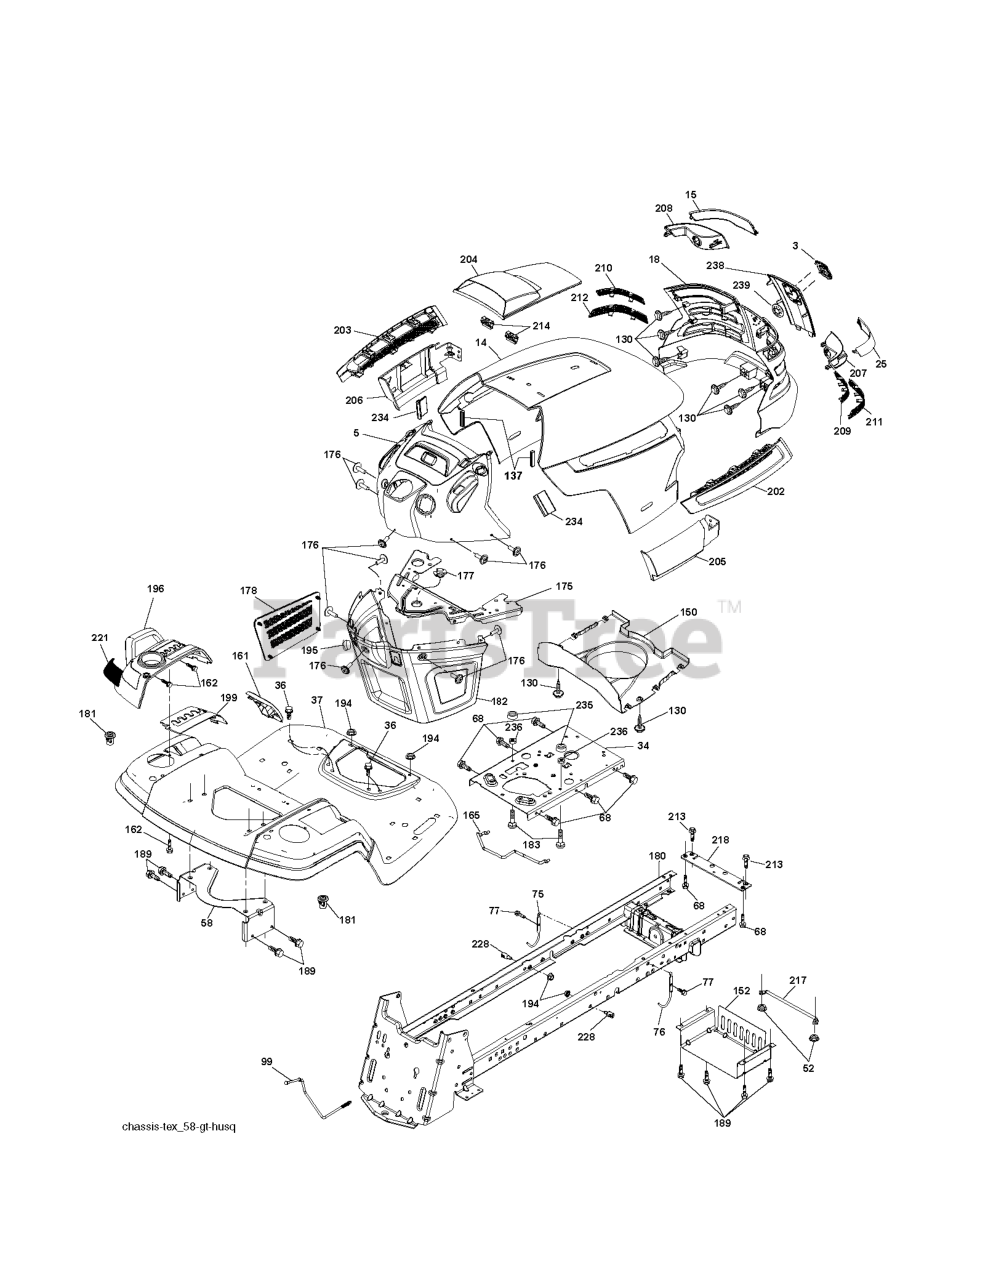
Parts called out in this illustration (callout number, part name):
3	RP LOGO
5	DASH.ASM.HUSQ.GT.E.RECT.W/CK
14	HOOD
15	LENS.LH.TEX.GT.HUSQ.CL
18	GRILL.ASM.HUSQ.TG/CRD.W/TRIM
25	LENS.RH.TEX.GT.HUSQ.CL
34	PLATE.ENGINE.WELDED.CHASSIS
36	SCREW 5/16"
37	FENDER.PNT.TX.GT.CH/FW.ORANGE
52	LOCKNUT
58	BRKT.SUPPORT.FNDR/TANK
68	Screw 5/16-18 x 1/2 Hex, Self Tapping 5/16-18 x 1/2
75	ROD UPSTOP
76	ROD UPSTOP
77	SCREW 3/8-16X1
99	ROD.BYPASS.HYDRO.0510/0610.GT
130	SCREW
137	BUMPER DASH
150	AIR.DUCT.HOOD.TEX.GT.HUSQ
152	SHIELD.BROWNING.W/TEX
161	CONSOLE.FUEL.WINDOW.HU
162	SCREW.HI-LO.CONSOLE
165	SUPPORT.TANK.REAR.W/TEX
175	PLATE.CROSSMEMBER.HUSQ
176	SCREW.#10-24X5/8.RN.QU
177	BUSHING, STEERING
178	CARGO.ASM.NET.TXGT.W/C
180	CHASSIS.GT.SLOPED.DRAWBAR.
181	BUSHING.MNT.FEND.CRGO.
182	DASH.LOWER.COMMON.12V.
183	BOLT.5/16-18X1-1/4 FULL.THREAD
189	SCREW
194	NUT LOCK HEX FLANGE 5/16-18
195	PLUG.HOLE.DASH.LOWER.12V.BLK
196	RP CONSOLE.ASM.DECKLFT.W/
199	PLATE.DECK.LIFT.HUSQVARNA.GT
202	VENT.SIDE.HOOD.HUSQ.RH.GREY
203	VENT.SIDE.HOOD.HUSQ.LH.GRAY
204	VENT.TOP.HOOD.HUSQVARN
205	SKIRT.HOOD.SIDE.HUSQ.RH.GREY
206	SKIRT.HOOD.SIDE.HUSQ.LH.GREY
207	BEZEL.RH.TEX.GT.HUSQ
208	BEZEL.LH.TEX.GT.HUSQ
209	INSERT.HEX.GRILL.HUSQ.GREY
210	INSERT.HEX.GRILL.HUSQ.
211	INSERT.HEX.GRILL.HUSQ.
212	INSERT.HEX.GRILL.HUSQ.
213	BOLT
214	CLIP.RETAINER.TINNER.
217	ROD PIVOT CHASSIS/HOOD
218	X-PIECE.HOOD.STOP.NON/
221	REFLECTOR.LH.TEX GT HU
228	STUD.FASTNER.W/ANTI-ROTATE
234	BUMPER.HOOD.TEX.HUSQVARNA
235	SPACER FENDER
236	NUT.CENTERLOCK.5/16-
238	TRIM.HUSQ.TG/CRD.SERVICE
239	NUT PUSH M
